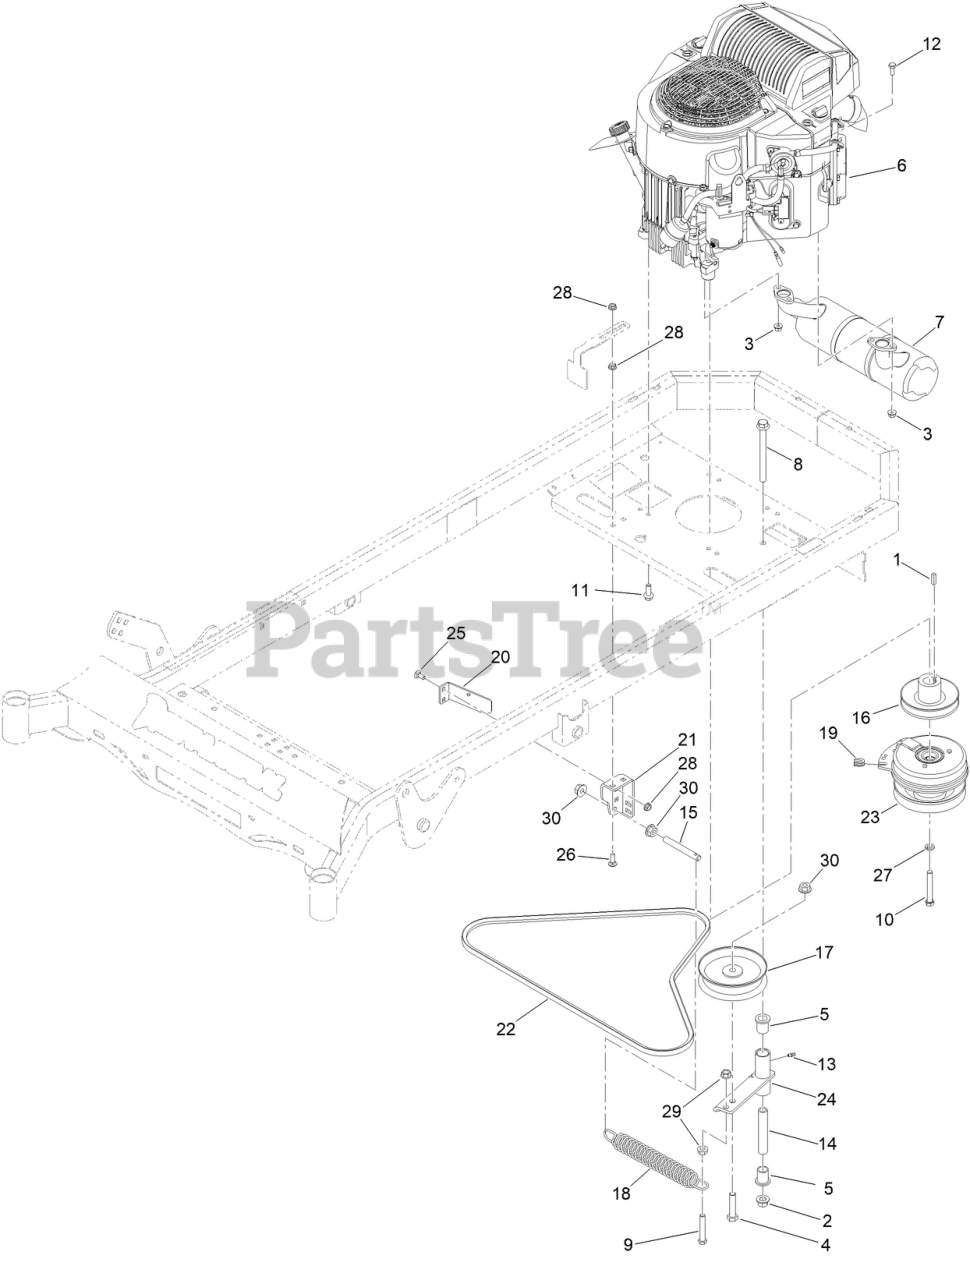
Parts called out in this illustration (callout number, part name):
2	NUT-LOCK
3	NUT-HF
4	SCREW-HH
5	3/4IN ID X15/16IN OD X 1-1/8IN FLNG BUSH
6	KAWASAKI FR730V-DS27-R ENGN
7	2019 EXHAUST SYST FOR KAWI FR FS AND FT
8	1/2-13 X 5-1/2 HEX FLANGE BOLT GR 8 ZY
10	7/16-20 X 3 HEX C/S GR 8 ZC YELLOW
11	3/8-16 X 1-1/8 IND HWH W/SERR TRI LOB ZY
12	M8-1.25 X 20MM HEX FLANGE BOLT ZINC 10.9
13	1/4IN DRIVE TYPE GREASE FITTING YZ
14	MWR INNER IDLER SPACER
15	MWR PUMP IDLER SPRING TENSIONER
16	MWR HYDRAULIC PUMP DRIVE PULLEY (B-BELT)
17	5-3/4IN IDLER PULLEY 7/16IN SPACER ASSY
18	MWR DECK SPRING
19	MWR CLUTCH ROTATION STOP BRKT SLEEVE
20	MWR CLUTCH ANTIROTATION BRKT BLACK
21	MWR PUMP IDLER TENSIONING BRKT BLACK
22	MWR PUMP BELT RT A X 68.25IN EFF LNGTH
23	WARNER PTO CLUTCH
24	MWR PUMP IDLER ASSY BLACK
25	BOLT-CARR
26	BOLT-CARR
27	WASHER-LOCK
29	NUT-HF
30	NUT-HHF
